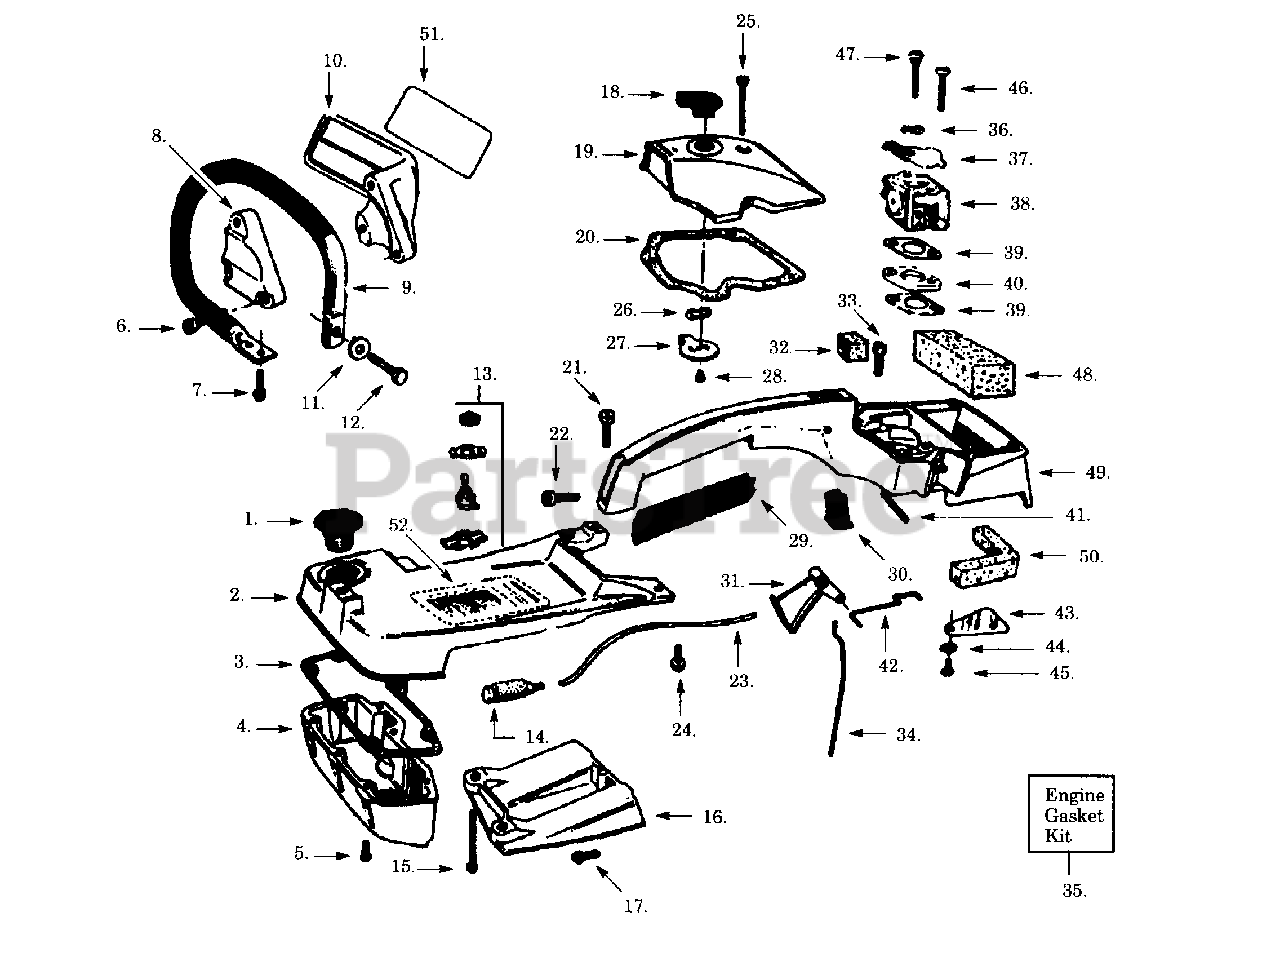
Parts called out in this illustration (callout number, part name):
1	Fuel Cap Ass'y.
2	Fuel Tank Top
3	Fuel Tank Gasket
4	Fuel Tank Bottom
8	Handguard Cap
9	Front Handlebar
10	Handguard
13	Start/Stop Switch
14	Fuel Pick-up Ass'y.
16	Cylinder Shield
18	Choke Knob
19	Carburetor Cover
20	Carb. Cover Gasket
23	Line Kit (Bulk 8133)
26	Wave Washer
27	Choke Lever
29	Handle Grip
30	Oil Pump Button
32	Throttle Wire Boot
34	Oil Pump Push Rod
35	Engine Gasket Kit
36	Wave Washer
37	Choke Shutter
38	Carburetor
39	Carb. Gasket
41	Trigger Pin
42	Throttle Rod
48	Air Filter
49	Handle & Carb. Hsg.
50	Dust Seal
51	Handguard Decal
52	Instruction Decal
